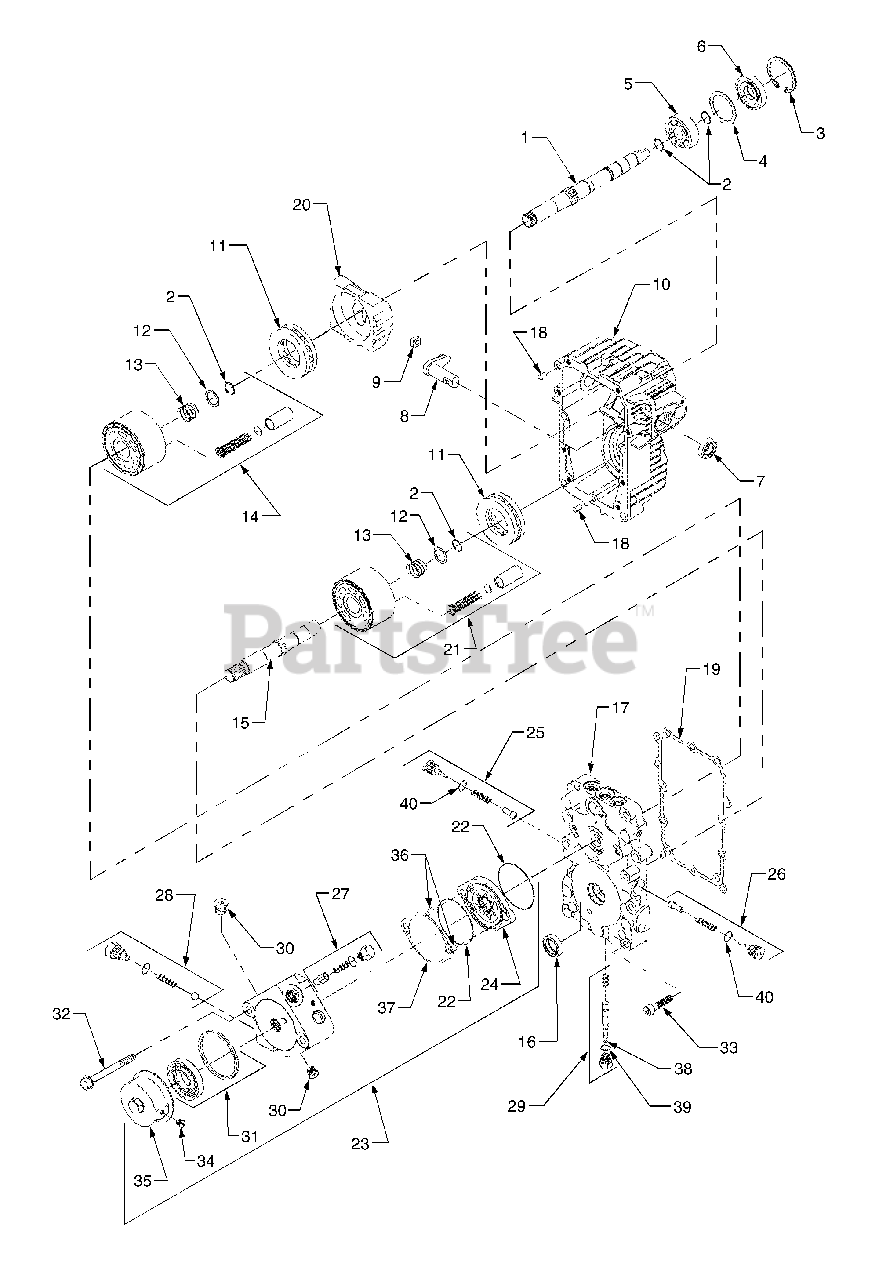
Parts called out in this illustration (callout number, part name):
1	Pump Shaft Service Kit
2	Ring, Wire Retaining
3	Ring, Retaining
5	Bearing, Ball
6	Seal, Lip
8	Arm, Trunnion
9	Guide, Slot
10	Housing Assembly
11	Bearing Assembly, Thrust Ball
12	Washer, Block Thrust
13	Spring, Block
14	Kit, Pump Cylinder Block
15	Shaft, Motor
17	Kit, Center Section
19	Gasket, Center Section
20	Swashplate, Variable
21	Kit, Motor Cylinder Block
23	Kit, Auxiliary Charge Pump
24	Gerotor & Housing Assembly
25	Kit, Check Valve
26	Kit, Check Valve w/ .044 Orifice
27	Kit, Check Relief
28	Kit, Auxiliary Relief Valve
29	Kit, Bypass Valve
31	Kit, Auxiliary Filter
32	Screw, Flange Head Cap, M8 x 60
33	Screw, Socket Head Cap
35	Cover, Filter
37	Shim, Charge Pump
38	O-Ring-Order Seal Kit P/N HG-2510010
39	O-Ring-Order Seal Kit P/N HG-2510010
40	O-Ring-Order Seal Kit P/N HG-2510010
